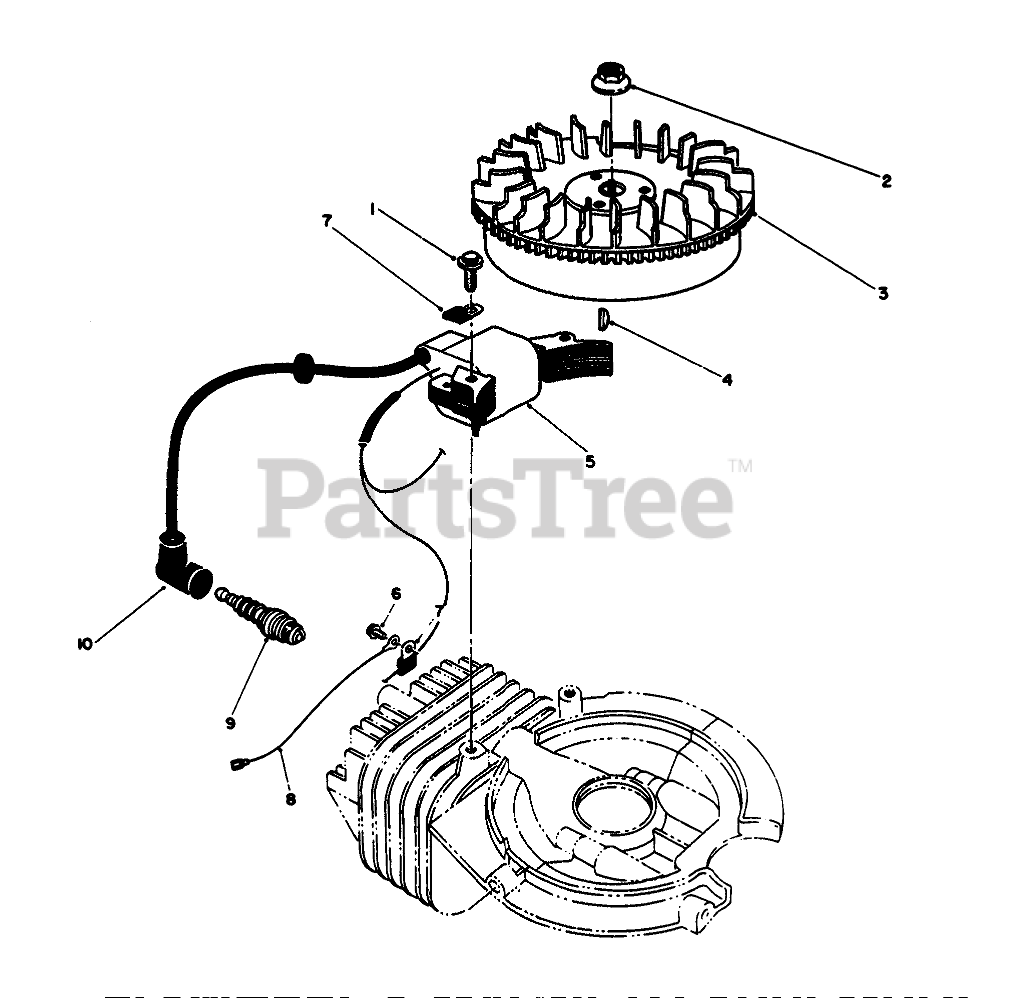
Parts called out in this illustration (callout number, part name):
1	SCREW
3	FLYWHEEL
7	CLAMP
9	Sparkplug
10	CAP-SPARKPLUG
